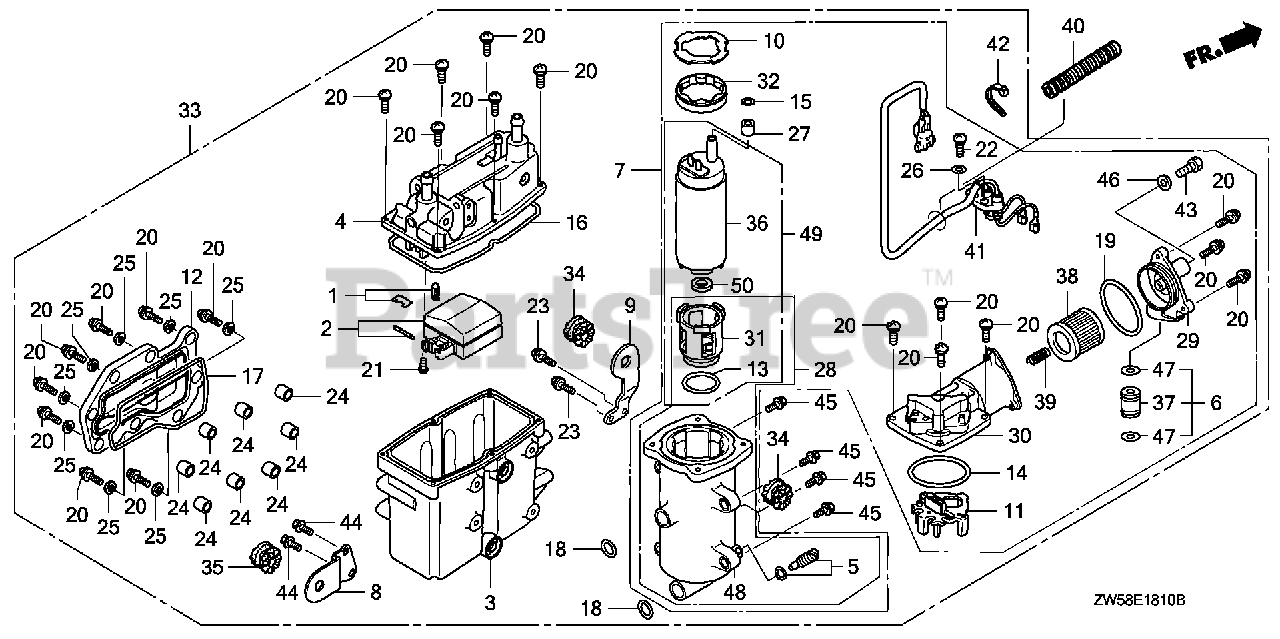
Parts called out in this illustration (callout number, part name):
1	VALVE SET, FLOAT
3	BODY, CHAMBER
5	SCREW SET, DRAIN
7	PUMP UNIT SET A, FUEL (MSDS)
8	STAY, PLATE (A)
9	STAY, PLATE (B)
12	COVER, WATER JACKET
15	O-RING
15	O-RING (7.3X2.2) (NOK)
20	SCREW-WASHER
21	SCREW, PAN
22	SCREW, WASHER
23	SCREW, WASHER
24	COLLAR, SET
25	WASHER, PLAIN
26	WASHER, PLAIN
28	CASE, PUMP
29	COVER B, PUMP
30	COVER, PUMP (A)
33	SEPARATOR ASSY., VAPOR
34	GROMMET, VAPOR SEPARATOR
35	GROMMET, VAPOR SEPARATOR
36	PUMP UNIT, FUEL (MSDS)
37	JOINT, FUEL PIPE
38	SCREEN, FUEL STRAINER
39	SPRING, SET
40	TUBE, CORRUGATE (7MM)
43	BOLT, SEALING (6MM)
44	BOLT, FLANGE (6X16)
45	BOLT, FLANGE (6X25)
46	WASHER, SEALING (6MM)
47	O-RING (7.8X1.9) (ARAI)
48	CASE, PUMP
